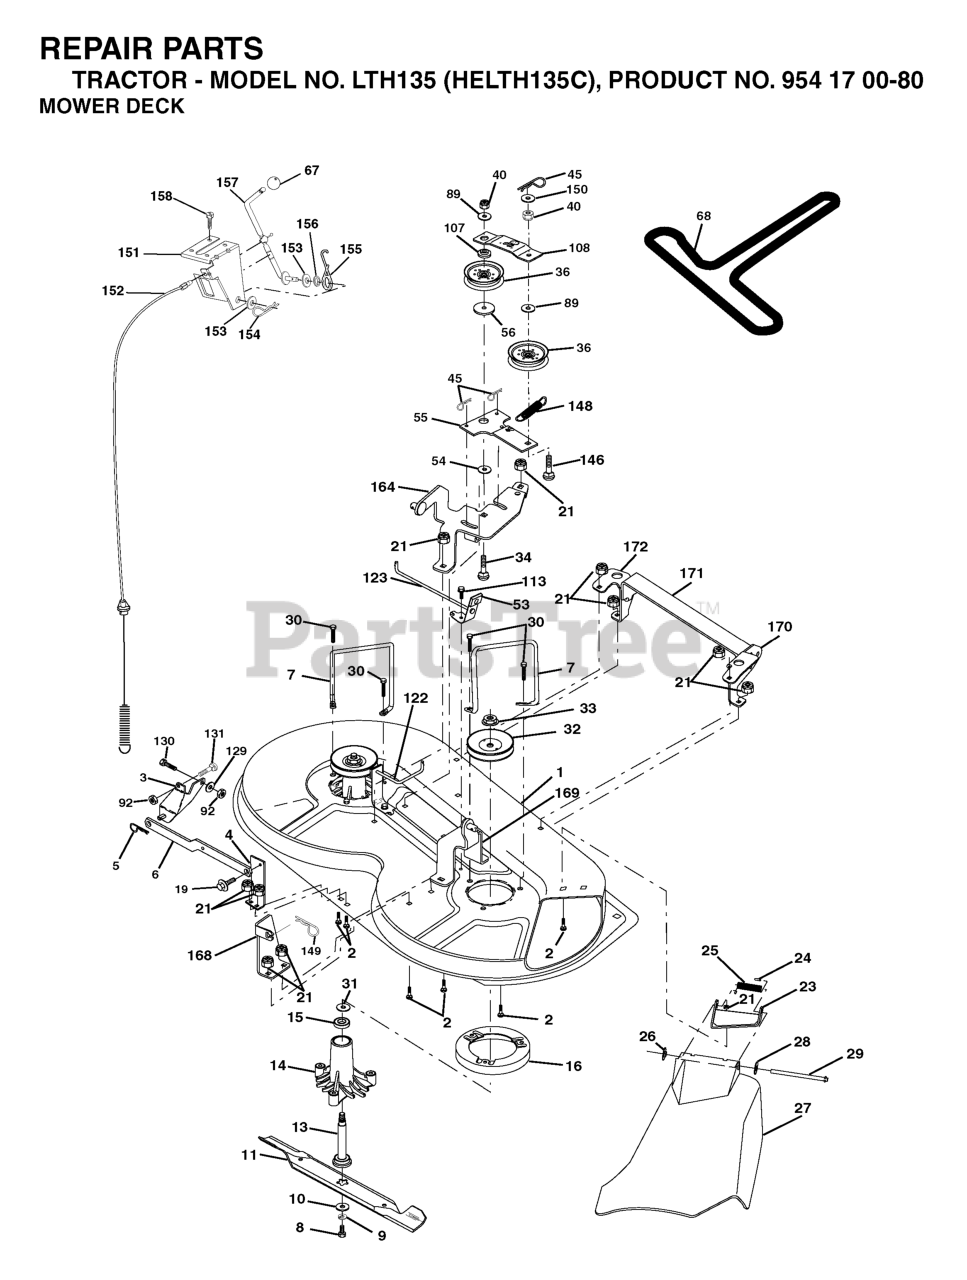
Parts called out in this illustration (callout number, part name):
2	RP BOLT 5/16-18 X3/4 ZN/YEL GR
3	BRKT ASM SWAY BAR
5	RETAINER-SPRNG RB
6	BAR SWAY DECK
8	BLADE BOLT
9	LOCKWASHER
10	WASHER.BLADE
11	BLADE, HI-LIFT 36" PREMIUM
13	SHAFT ASM VENT
14	HOUSING.MANDREL.VENTED (MACHD)
16	STRIPPER.MANDREL.ROUND.BLACK
19	BOLT SHD 5/16-18
21	LOCKNUT
23	BRACKET ASM DEFLECTOR
24	CAP-SLEEVE LT
25	SPRING TORSION
26	NUT PUSH M
27	CONSOLE.STLT.5SP.BLK
28	Washer 11/32 x 5/8 x 16 Ga SD
29	HINGE ROD
30	SCREW, WASHER HEAD
31	WASHER
32	PULLEY, MANDREL
33	NUT, FLG TOPLOCK 9/16"
36	FLAT IDLER PULLEY
45	RETAINER M
53	BRAKE ASSEMBLY
56	SPACER.RETAINER.MOWER
67	KNOB T (3/8 HOLE)
68	V-BELT.MOWER.
89	WASHER GT
92	NUT
107	SPACER.IDLER.ARM
108	STIFFENER.IDLER.ARM
113	Screw 5/16-18 x 1/2 Hex, Self Tapping 5/16-18 x 1/2
129	WASHER
131	BOLT D
146	BOLT, CARRIAGE IDLER
148	IDLER RETURN SPRING
149	SPRING.RETAINER.YELLOW.ZINC
151	BRACKET.CLUTCH.CABLE
153	WASHER FLAT 3/8"
154	SPRING RETAINER
155	SPRING RETENTION LEVER
156	SPACER.CLUTCH.CABLE
157	ROD CLUTCH CABLE 3/8"
158	SCREW
171	BRACE.SUPT.SUSP.FRT.CRD
